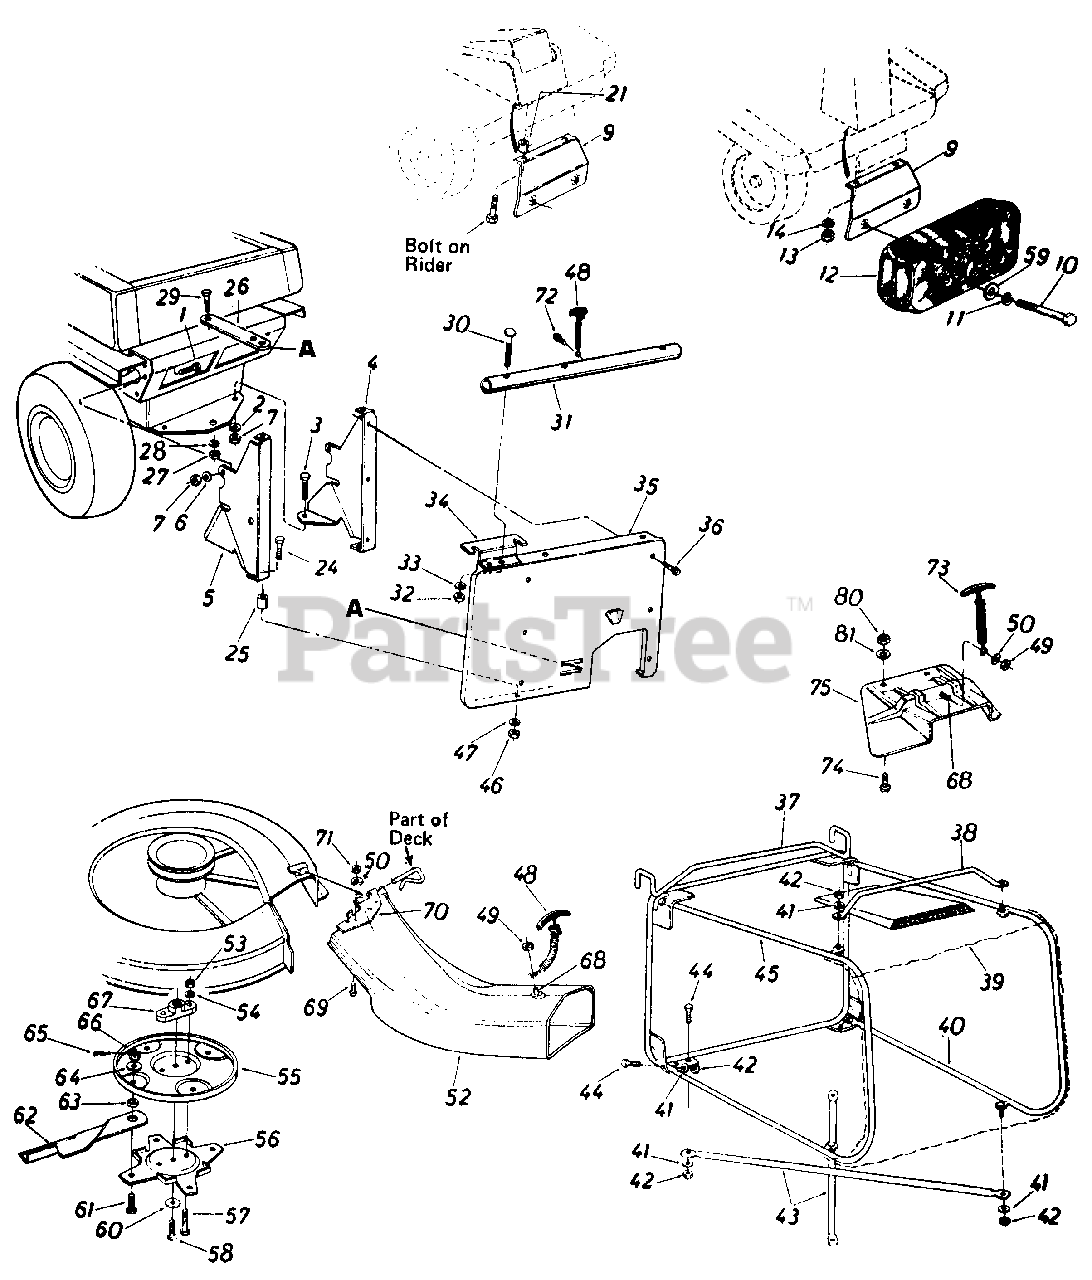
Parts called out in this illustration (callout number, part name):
1	Hex Bolt 5/16-18 x 1.0" Lg.
2	L.-Wash. 5/16" I.D.
3	Hex Bolt 5/1618 x 1.0" Lg.
4	Catcher Support Brkt - R.H.
5	Catcher Support Brkt - L.H.
6	L.-Wash. 5/16" I.D.
7	Hex Nut 5/16-18 Thd.
9	Counterweight Support Brkt. Ass 'y .
10	Hex Bolt 3/8-16 x 4.5" Lg.
11	Belleville Wash. .40" I.D. x .88" 0. D.
12	Counterweight 38 lbs.
13	Hex Nut 5/16-18 Thd.
14	L.-Wash. 5/16" I D
21	Spacer .380" I.D x 1.0" O.D. x .32" Lg.
24	Hex Bolt 5/16-18 x 1.50" Lg.
25	Spacer .380" I.D. x .47" O.D. x 1.0" Lg.
28	L.-Wash. 1/2" I.D.
29	Hex Bolt 1/2-20 x 1.0" Lg.
30	Curved Carriage Bolt 5/16-18 x 1.75" Lg.
33	L.-Wash. 5/16" I.D.
34	Grass Catcher Support Plate
35	Rear Discharge Panel
36	Hex Wash. Hd. Self Tap. Scr. 1/4- 20 x .50" Lg.
37	Grass Catcher Frame Ass'y.
42	Hex L. Nut 1/2-20 Thd
43	Bottom Cross 8race
44	Hex Bolt 1/4-20 x .62" Lg.
47	L-Wash. 5/16" I.D.
48	Hook Latch Ass'y.
49	Hex L.-Nut 1/4-20 Thd.
50	L.-Wash. 1/4" I.D.
52	R.D. Banana Chute Ass'y.
53	Hex Nut 5/16-24 Thd.
54	L.-Wash. 5/16" I.D.
55	Upper Blade Disc
58	Hex Bolt 3/8 24 x l.O" L.
59	Fl.-Wash. .39" I.D. x 1.12" O.D.
60	Bell.-Wash. 39" I.D. x 1.38"
61	Shld. Bolt. .50" Dia. x .360 Spec.
62	30" Blade Tip
63	Spacer .505" 1. D. x .75" O.D. x 1.25" Lg.
64	Fl. Wash. .50" I.D. x 1.25" O.D.
65	Cotter Pin 3/32" Dia. x 1.0" Lg.
66	Hex Slotted Nut 1/2-20Thd.
67	Blade Adapter
68	Hex Bolt 1/4-20 x .50" Lg.
69	Truss Mach. Scr. 1/4-20 x .50" Lg.
72	Hex AB Tap Scr. 1/4 x .62" Lg.
73	Hook Latch Ass'y. 7" Lg.
74	Truss Mach. Scr. 1/4-20 x 50" Lg.
75	R D Chute Extension
80	Hex L. Nut 1/4-20Thd.
81	Fl.-Wash. .281" I.D. x .50" O.D. x .063
